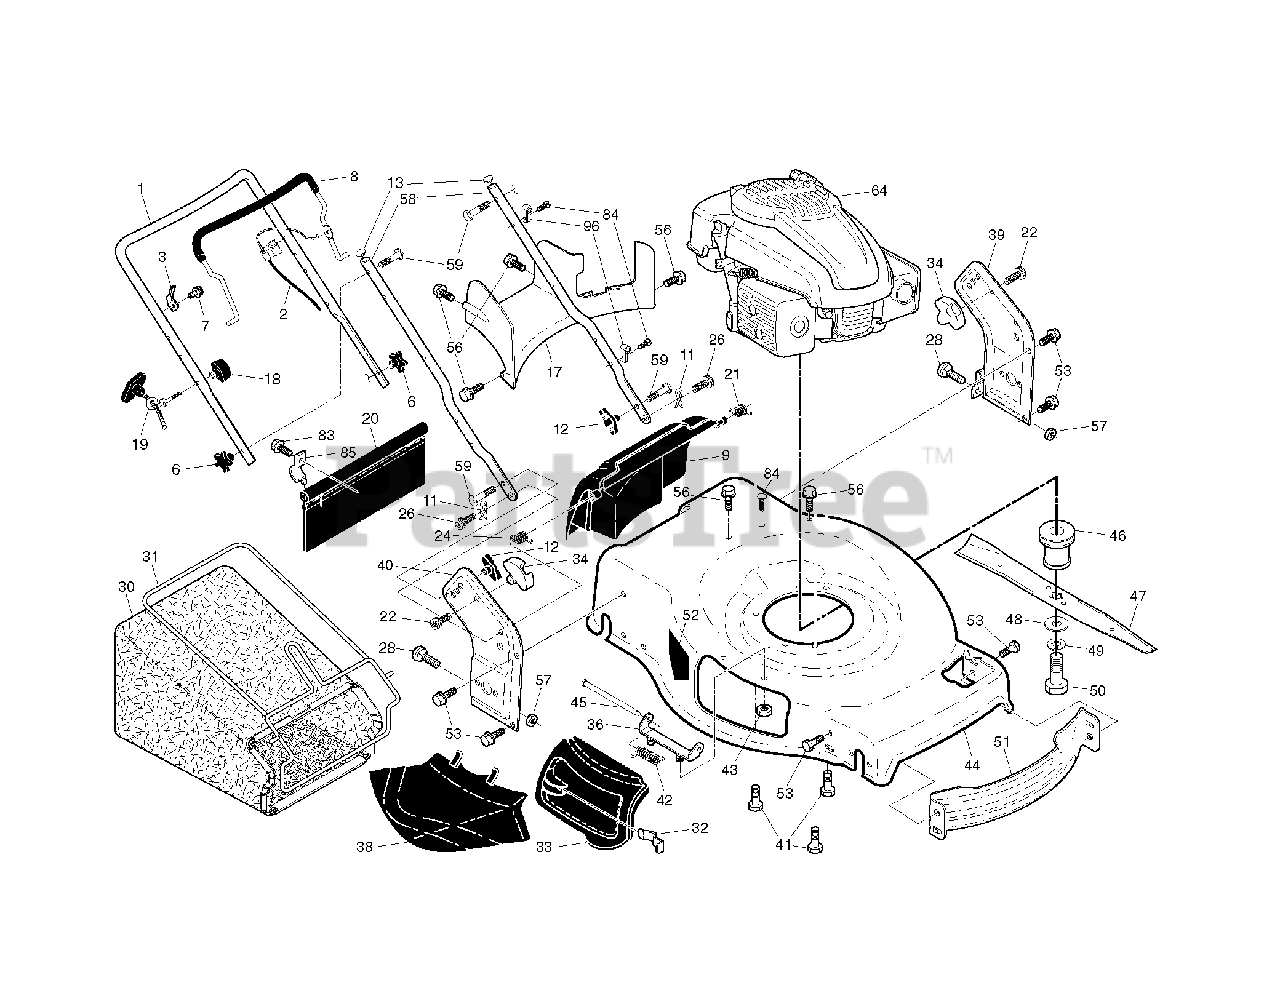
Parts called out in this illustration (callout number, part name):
1	HANDLE.UP.DST.SS/VS.FG/RG.NHB
2	Cable, MZR Rgd Plus Strt
3	BRACKET.UPSTOP.RT
6	KNOB.HANDLE.PLASTIC.STAR.BLACK
8	Bail, Om Strt Mzr Marig 421
9	DOOR.REAR.22+GEN.RG.EBA.BLK
11	COTTER.HAIRPIN.DOOR/HANDLE.PIV
13	PLUG.PLASTIC.7/8".14-20.GAUGE
17	BAFFLE.REAR.22+RGD.AWD.PLASTIC
18	T-KNOB.NEW ROPE GUIDE
19	Rope Guide, Blk Zinc Chrom
20	SKIRT.REAR.22PLUS.RGD.LW.2012
21	SPRING.LH.GRAY
22	SCREW.PAN.HEAD.#10
24	SPRING.RH.GRAY
26	SCREW,DOOR/HANDLE.PIVOT
28	Carriage Bolt, 5/16-18 X 5/8
30	GBAG.A1640416S.BLK.PPRO.MRG.
31	Grass Bag Frame, 22+ Black
32	LATCH.DOOR.ZINC
33	DOOR.MULCH.22.BLACK.MULTI-BRAN
34	BRACKET.GRASSBAG.ATTACHING.BLK
36	BRACKET.ASM.HINGE.21.FWGD.
38	DEFLECTOR.CLIPPING.22.BLACK
39	Handle Bracket Assembly, LH 22+ Black
40	Handle Bracket Assembly, RH 22+ Black
41	BOLT 3/8-16X1-1/8
42	SPRING.TORSION
43	NUT.HEX.FLANGE.1/4
44	Mower Deck Shell, 22"+ Awd Mc Wo Blk Tri
45	ROD.HINGE.21
46	ADAPTER.BLADE.25MM.3MPH
47	BLADE.22PLUS
48	WASHER,HARDEN
50	SCREW, HEX HD 3/8-24 X 1-3/8
51	BAFFLE.FRONT.22.PLUS
52	No Step Decal
53	BOLT.5/16HEX.WHS.HD
56	SCREW.HX.13X.750
57	NUT.FLANGE.5/16
58	HANDLE.LOWER.22+.BT.2PC.BLK
59	BOLT, HANDLE 5/16-18X1.75
83	TAPPING SCREW
84	FASTENER.PUSH.O.250X0.783
85	BRACKET.SKIRT.22+.BZP
96	CLIP.CABLE.BLK
